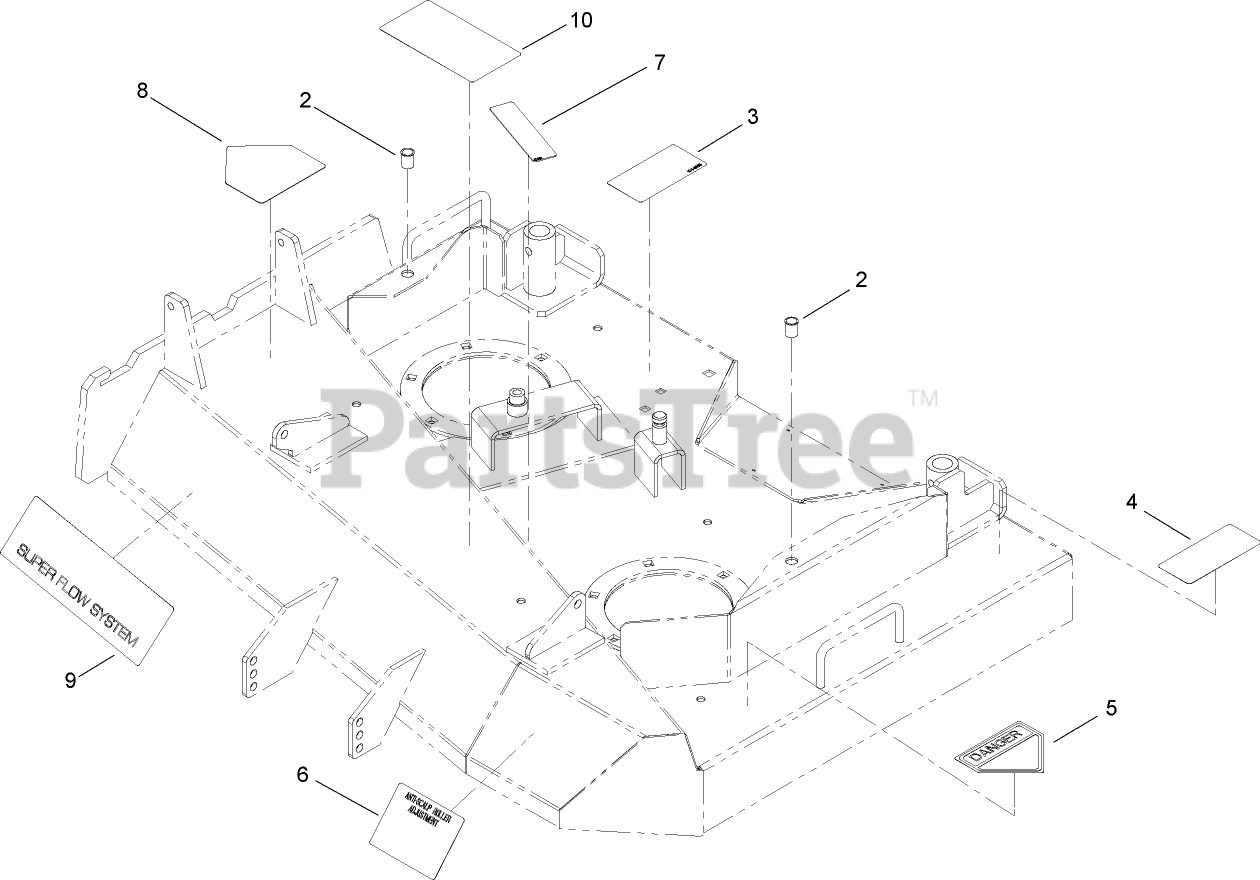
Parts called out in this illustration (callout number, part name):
2	INSERT-NUT
4	DECAL-TORQUE
5	DECAL-DANGER
6	DECAL-ANTI SCALP
7	DECAL-DANGER
8	DECAL-DANGER
10	DECAL-DANGER, THROWN OBJECT
